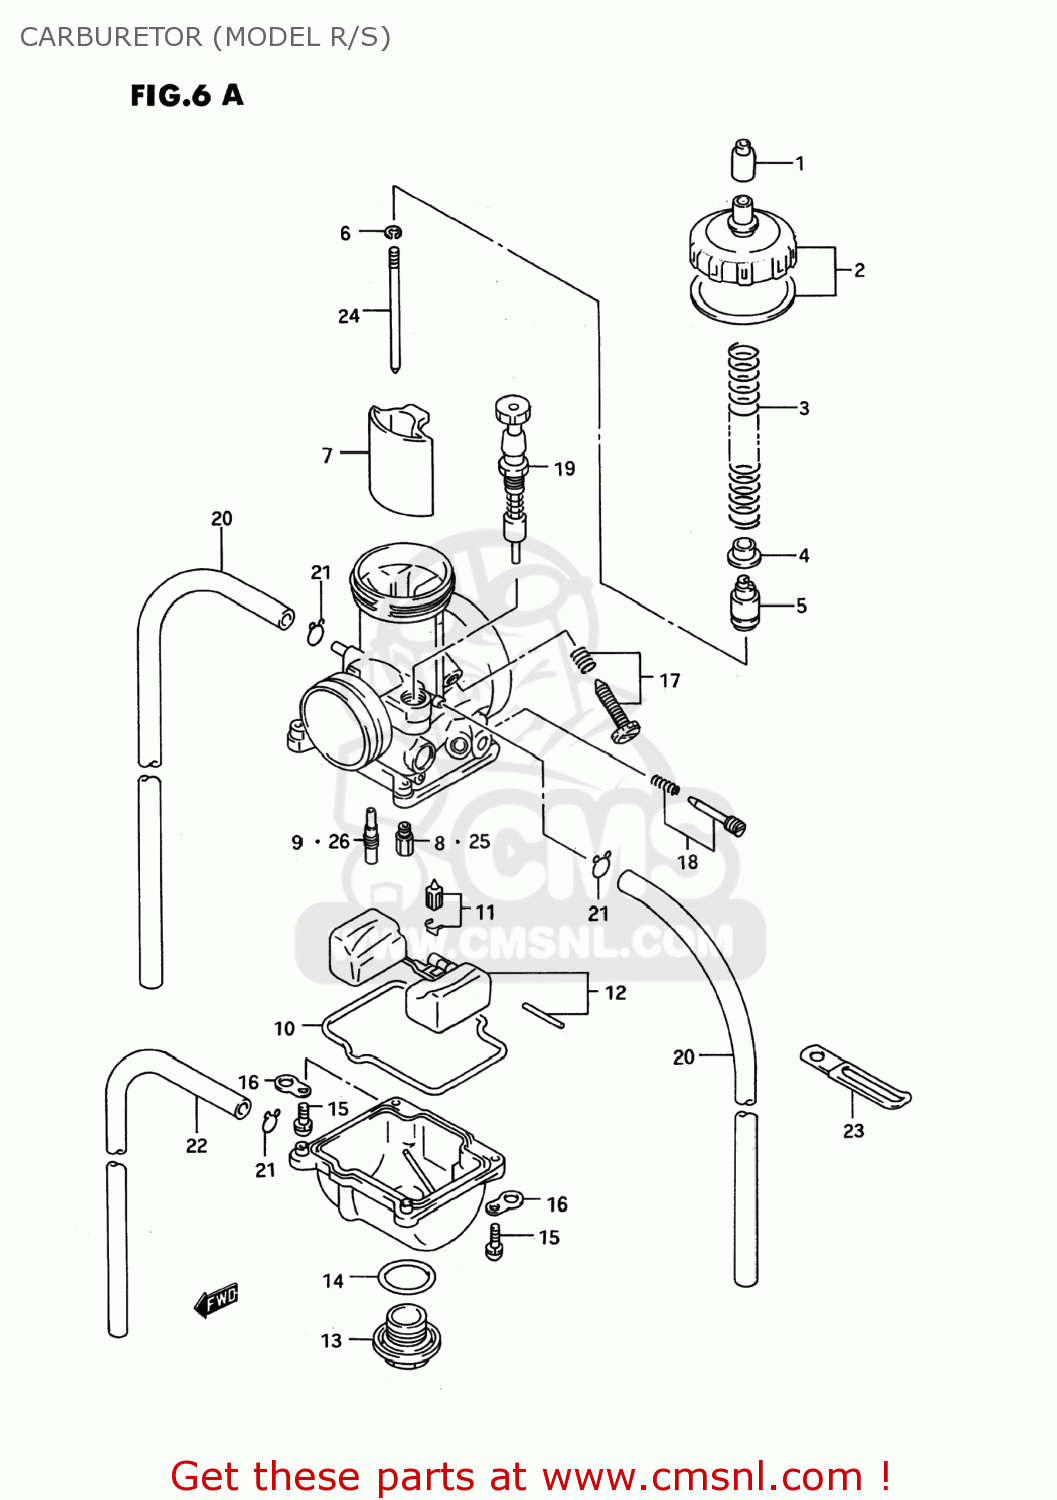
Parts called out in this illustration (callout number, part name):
1	CAP,CARBURETOR
2	CAP SET,TOP
3	SPRING,THROTTLE VALVE
4	COLLAR,THROTTLE VALVE
5	HOLDER,CABLE
6	CLIP,NEEDLE
7	VALVE,THROTTLE
8	JET,MAIN(168)
9	JET,SLOW(50)
10	GASKET,FLOAT CHAMBER
11	VALVE SET,FLOAT
12	FLOAT SET
13	BOLT,DRAIN
14	O RING
15	SCREW
16	PLATE
17	SCREW SET,STOP
18	SCREW SET,AIR
19	STARTER VALVE
20	HOSE (4X7X440)
21	CLIP
22	HOSE(3.5X6.5X600)
23	CLAMP
24	NEEDLE SET,JET
25	JET,MAIN(145)
26	JET,SLOW(35)
